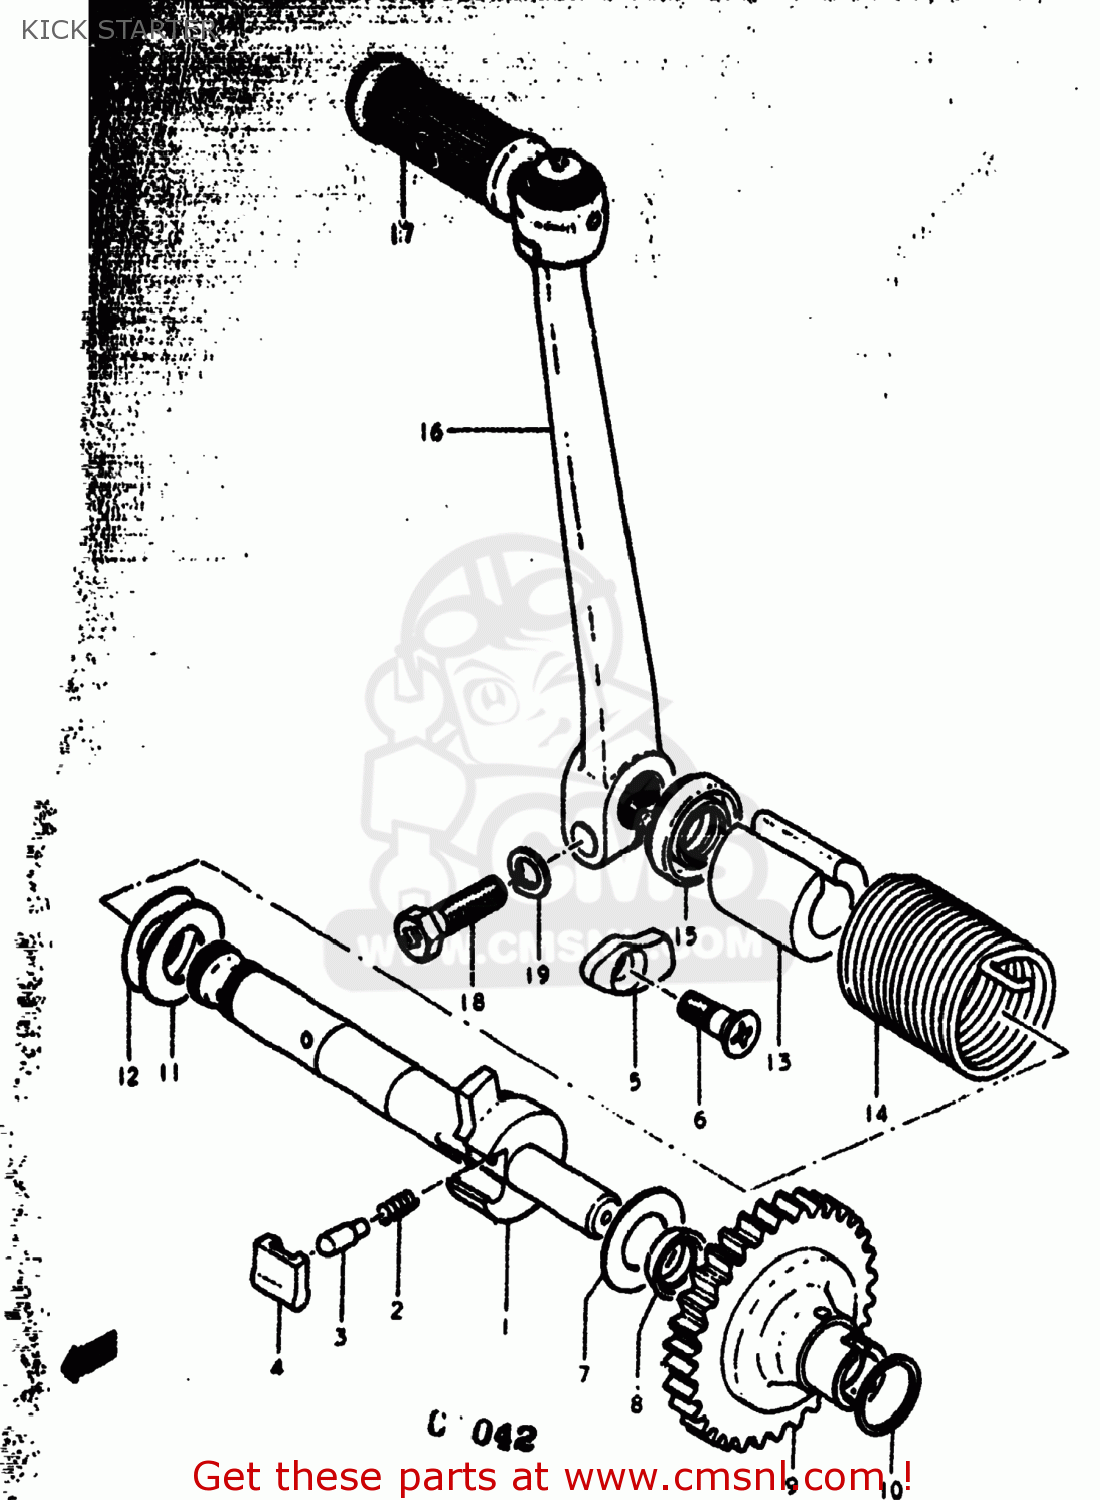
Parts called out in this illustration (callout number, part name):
1	SHAFT,KICK STARTER
2	SPRING
3	PIN(5X15.5)
4	PAWL,KICK STARTER
5	LIFTER,KICK STARTER PAWL
6	SCREW(6X19)
7	WASHER
8	OIL SEAL
9	GEAR,KICK STARTER DRIVE
10	WASHER(21X30X0.8)
11	WASHER
12	WASHER(16X30X0.5)
13	GUIDE,KICK STARTER SFT SPRING
14	SPRING
15	OIL SEAL K,L,M,A,B
16	LEVER ASSEMBLY,KICK STARTER
17	RUBBER,KICK STARTER PEDAL
18	BOLT
19	LOCK WASHER
